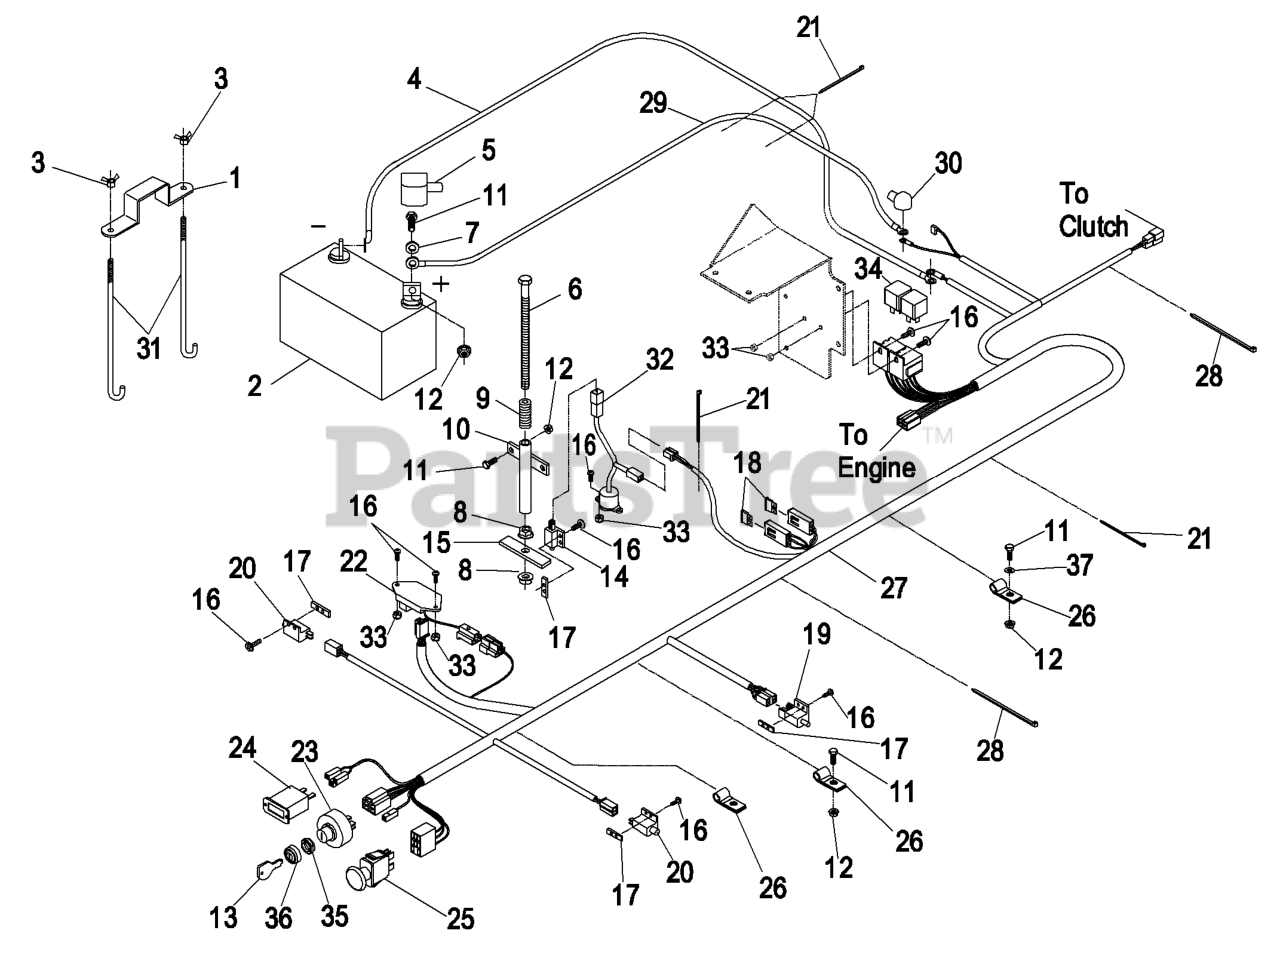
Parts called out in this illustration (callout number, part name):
3	WINGNUT
4	WIRE-GROUND
6	SCREW-HH
7	WASHER-FLAT
9	SPRING-SWITCH, SEAT
11	SCREW-HH
13	KEYS-IGNITION (SPARE PAIR
14	SWITCH-CLOSED, NORMALLY
15	PLATE-SWITCH, SEAT
16	SCREW-PPH
17	PLATE-TAPPED
18	FUSE-BLADE TYPE, 20 AMP
20	SWITCH-OPEN, NORMALLY
21	TIE-CABLE
22	MODULE-DELAY, SEAT
24	METER-HOUR
26	CLIP-LOOM
27	HARNESS,WIRE KC
28	TIE-PLASTIC
30	INSULATOR-SOLENOID
31	BOLT-HOLDDOWN
33	NUT-LOCK, NI
35	NUT-SWITCH, IGNITION
36	SEAL-SWITCH, IGNITION
37	WASHER-FLAT
